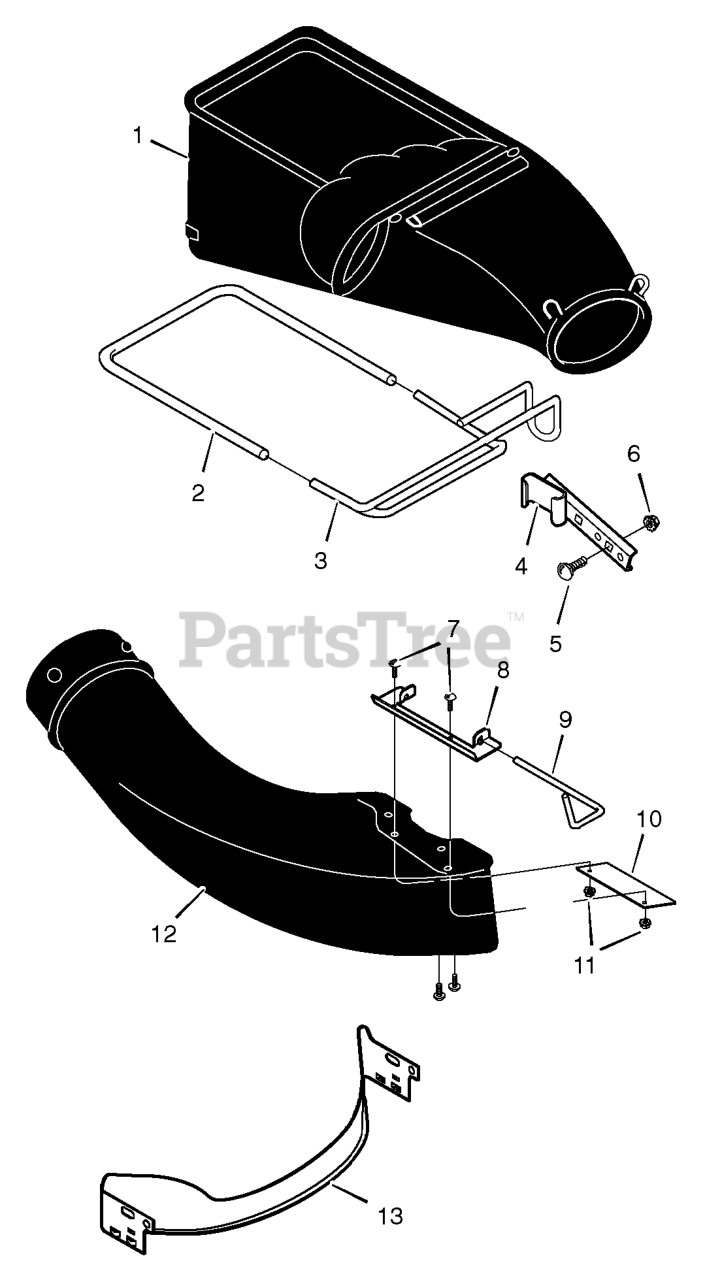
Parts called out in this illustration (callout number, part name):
1	Bag, Grass
2	Tube, Support
3	Frame, Bag
4	Bracket, Handle
5	Bolt, Carriage
8	Bracket, Chute
9	Pin, Locking
10	Plate, Inside
12	Extension, Chute
